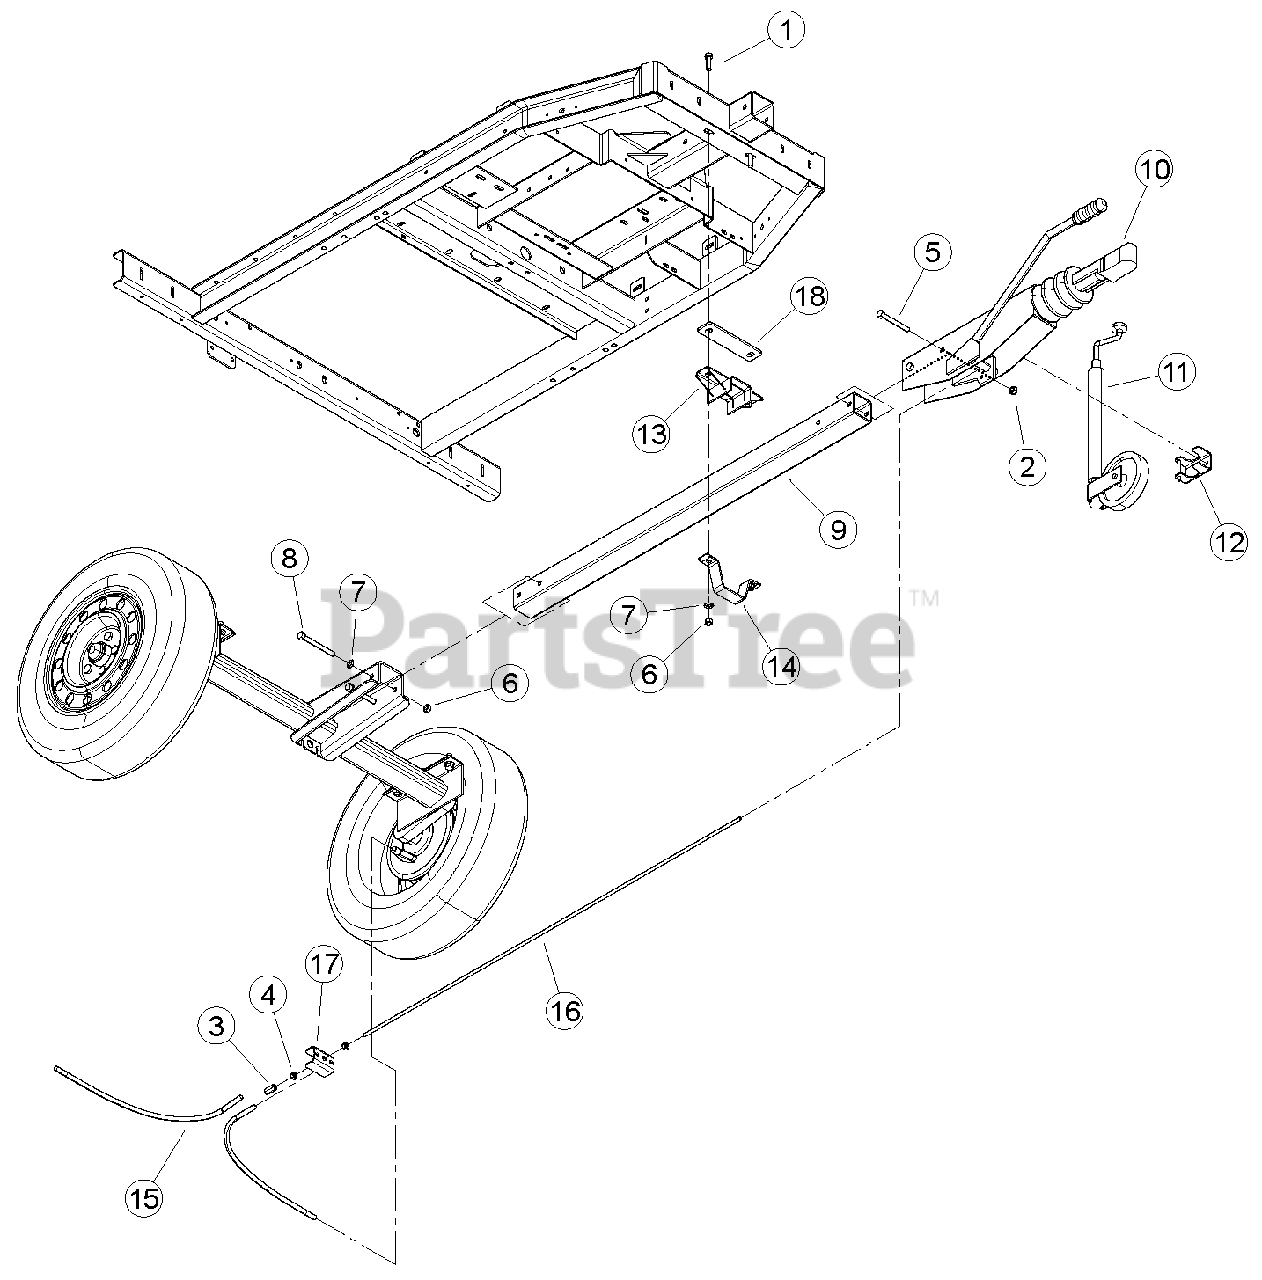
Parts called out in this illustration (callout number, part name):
1	BOLT, M12 X 1.75 X 40 GR8.8 HCPS
2	NUT, M12 X 1.75 HEX NYLOCK TYPE NEY ZP
3	BOLT, 12MM LUG FOR WHEELS
4	NUT, SPHERICAL M10 X 35MM
5	NUT, M10 HEX
6	BOLT, M12 X 100 CLASS 10.9
7	NUT, M12 HEX
8	WASHER, M12 FLAT
9	BOLT, M12 X 120 CLASS 10.9
10	DRAWBAR, 70MM X 70MM
11	COUPLER, 50MM W/ BRAKE HANDLE
12	JACK, JOCKEY WHEEL
13	CLAMP, JOCKEY WHEEL
14	MOUNT, FRONT DRAWBAR
15	CLAMP, FRONT DRAWBAR
16	CABLE, AXLE BRAKES SHORT
17	ROD, BRAKE CONTROL
18	BRACKET, BALANCE BAR
19	PLATE, DRAWBAR MOUNT
